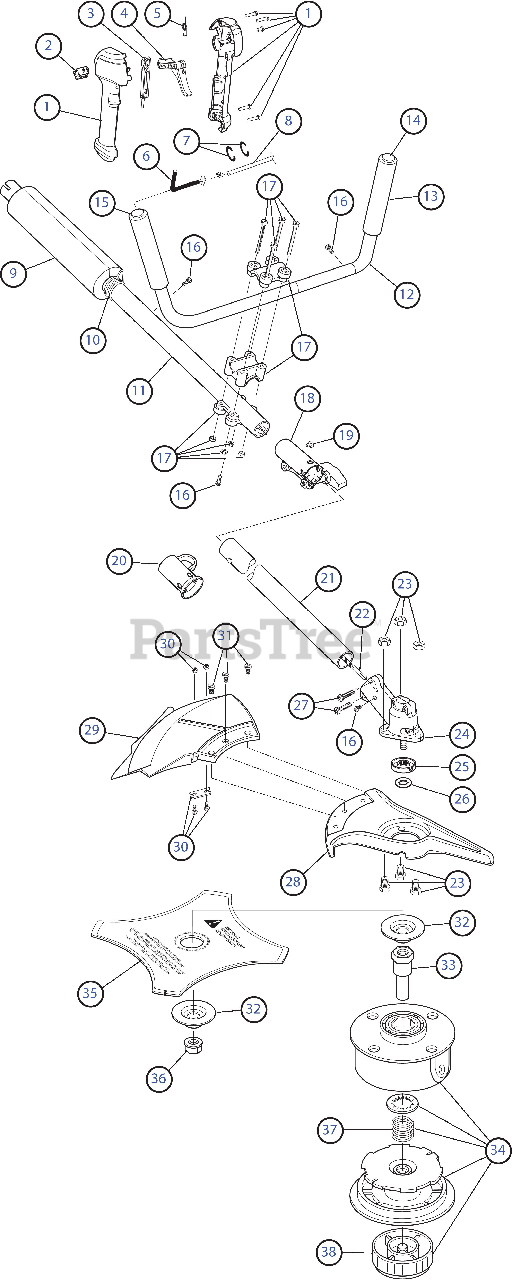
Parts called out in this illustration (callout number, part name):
1	Throttle Housing Assembly
2	Switch Assembly
3	Throttle Trigger Lockout
4	Throttle Trigger
5	Throttle Trigger Spring
6	Wire Cover
7	Wire Tie
8	Throttle Cable
9	Foam Grip and Cover
10	Harness Clip
11	Upper Drive Shaft
12	Bullhorn Handle Assembly
14	Tube Closure
15	Adapter
16	Anti-Rotation Screw
17	Handle Bracket Assembly
18	Split Boom Coupler
20	Hanger
21	Lower Drive Shaft Housing
22	Lower Flexible Drive Shaft
23	Shield Mount Hardware
24	Gearbox Assembly
25	Blade Driver
26	Palnut
27	Gear Box Screw
28	Blade Shield / Shield Mount
29	Shield Assembly
30	Blade Assembly
31	Shield Mounting Screws
32	Retaining Washer
33	Spool Shaft
34	Cutting Head Assembly
35	4-Tooth Blade
38	Bump Knob
